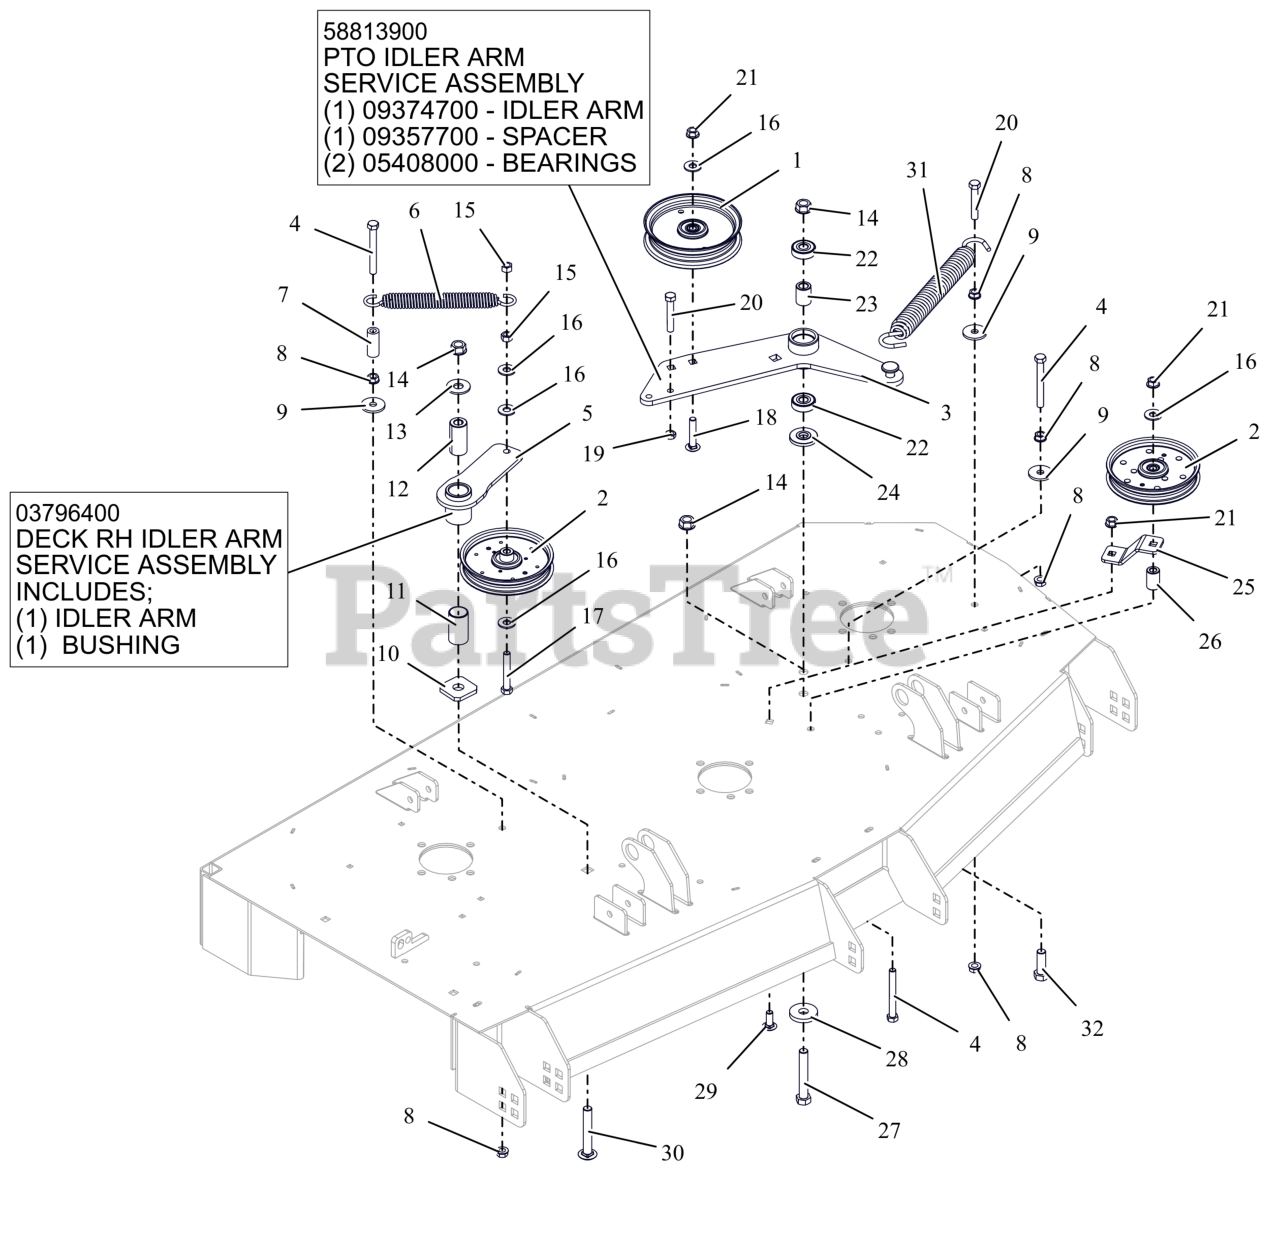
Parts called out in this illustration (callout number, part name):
1	IDLER- FLAT - 5.00" X .75"
2	IDLER- 5" FLANGED
3	WLDMT, IDLER ARM PT660
3	PTO IDLER ARM
3	SPACER .510 X .867 X 1.1485
3	BRG-BALL .500X1.38X.437
4	BLT, HEX .38-16X3.25 G5 ZCC
5	WMT, IDLER ARM - BLACK
5	ASM, IDLER ARM (DECK)
6	SPRING- EXTENSION
7	HOSE, .38 X 1.65
8	NUT, SPNLK-FLG .38-16 G5 ZCC
9	WSHR,FLT .406X1.375X.135 ZCC
10	WSHR-FLT .640X1.75X.250
11	BSHG, 1.00X1.125X1.937
12	BSHG, SPCR .502X.997X2.03 PM
13	WSHR,FLT .563X1.375X.109 ZCC
14	NUT-LK-CTR-FLG .500-13 GG ZCC
15	NUT-LK-CTR .38-16 ZC120
16	WSHR,FLT .438X1.00X.083 ZCC
17	BLT, HEX .38-16X2.50 G5 ZCC
18	BLT,RHSSN.375-16X2.00 G5 ZCC
19	NUT-JAM .375-16 G2 ZCC
20	BLT,HEX .38-16X2.25 G5 ZCC
21	NUT-LK-CTR-FLG .375-16 GF ZCC
22	BRG-BALL .500X1.38X.437
23	SPACER .510 X .867 X 1.1485
24	SPACER, IDLER ARM
25	PTO FIXED IDLER MTG BRKT -RED
26	BUSHING, SLV .380X.750X1.190
27	BLT,HEX .50-13X3.25 G5 ZCC
28	WSHR-FL-STL 0.557X1.625X0.25 ZCC
29	BLT,RHSSN .38-16X1.00 G5 ZCC
30	BTL,RHSSN .500-13 X 3.25 G5 ZCC
31	SPRING, EXTENSION
32	BLT,HEX .50-13X1.50 G5 ZCC
